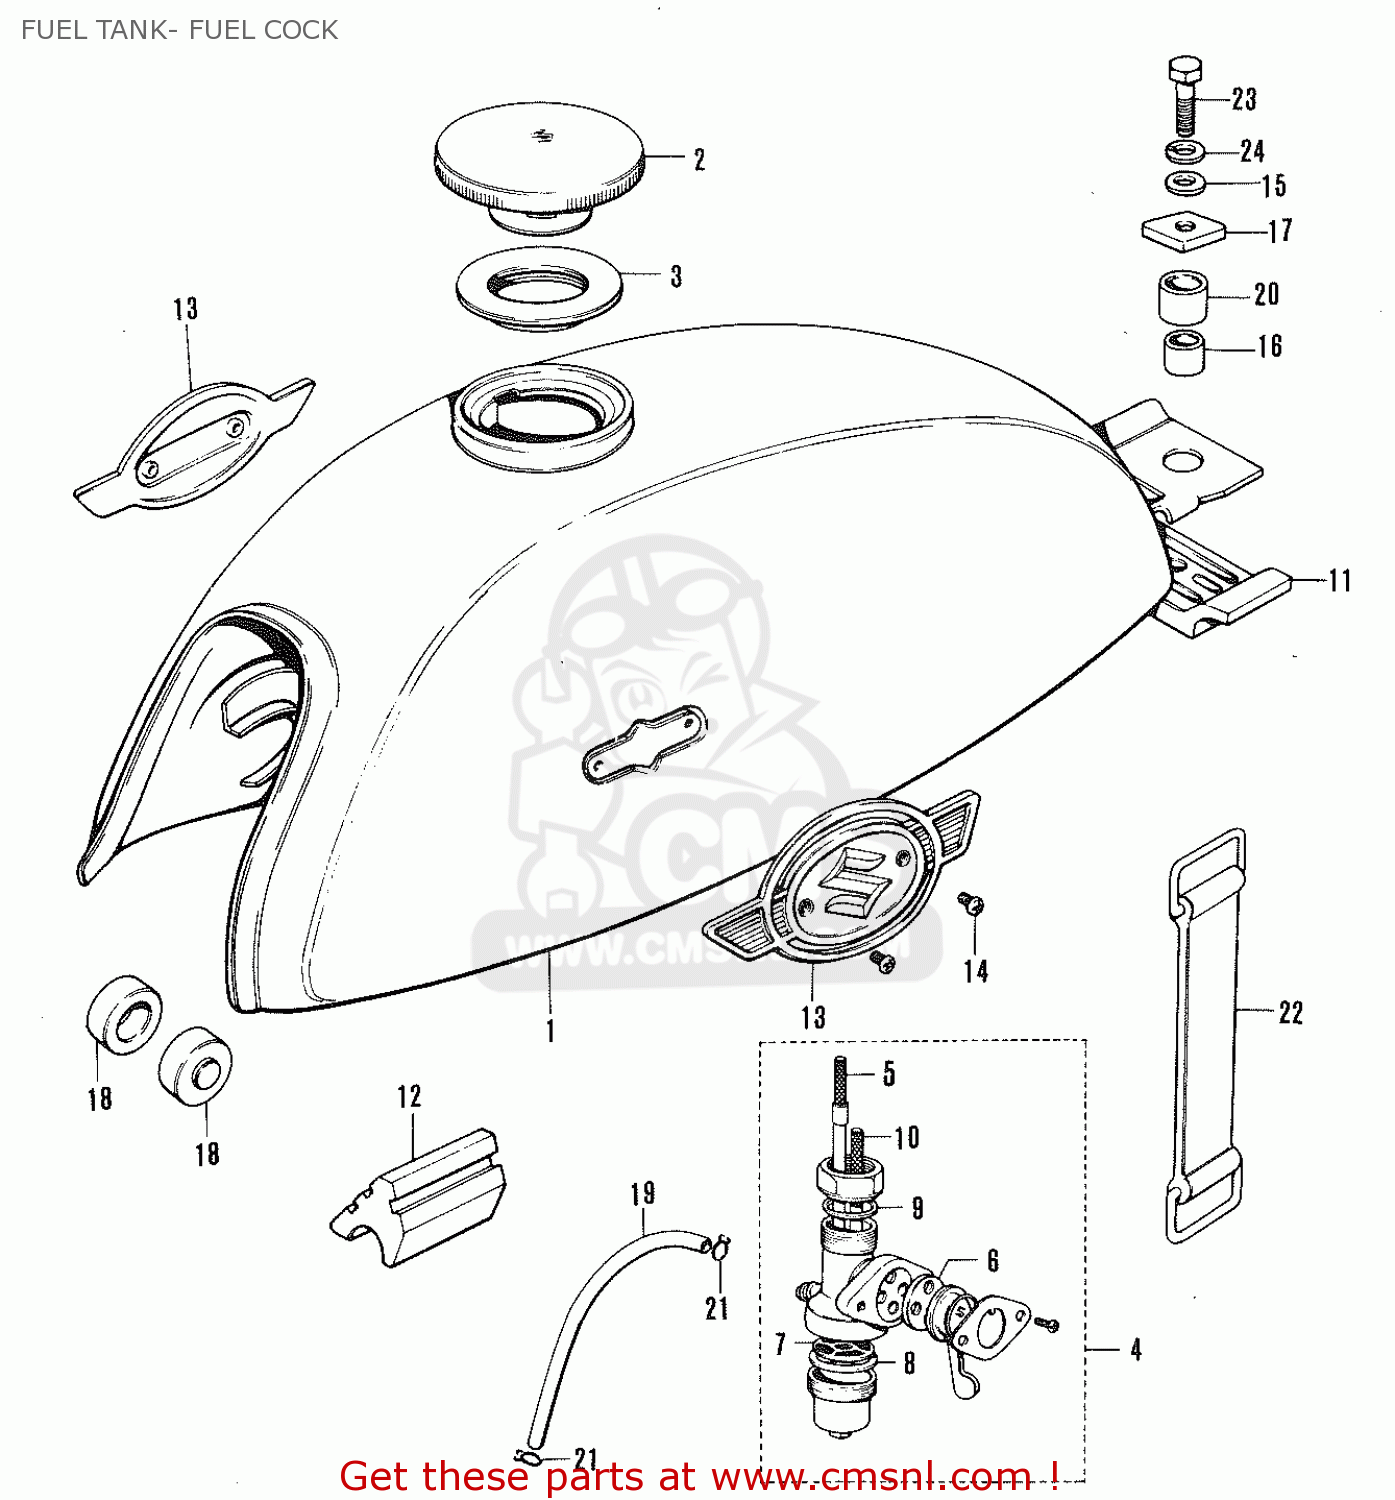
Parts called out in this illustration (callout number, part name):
1	TANK ASSEMBLY,FUEL
2	CAP SET,FUEL TANK
3	GASKET,FUEL TANK CAP (NAS)
4	COCK ASSEMBLY,FUEL
5	FILTER,FUEL
6	GASKET,LEVER (NAS)
7	NET,STRAINER
8	GASKET,STRAINER CUP (NAS)
9	GASKET,FUEL COCK (NAS)
10	NET,HOSE
11	CUSHION,FUEL TANK
12	CUSHION,FUEL TANK
13	TAPE SET,FUEL TANK
14	SCREW
15	WASHER (8.5X29X1.6)
16	SPACER
17	CUSHION
18	CUSHION
19	HOSE
20	HOSE
21	CLIP
22	BAND
23	BOLT
24	LOCK WASHER
